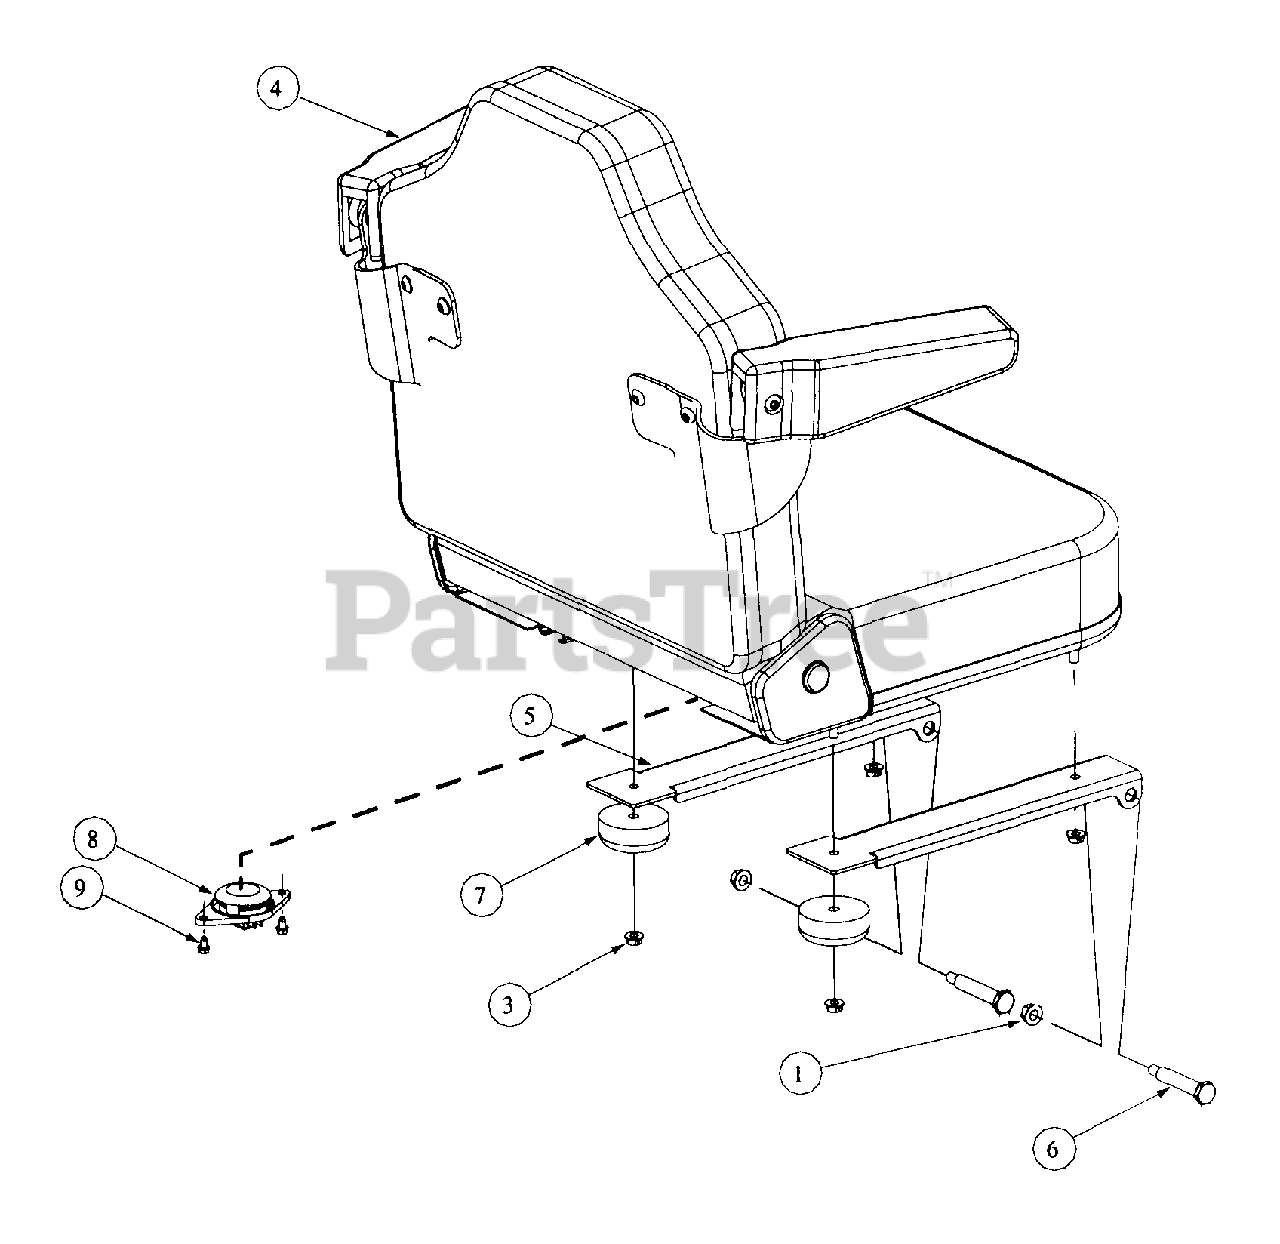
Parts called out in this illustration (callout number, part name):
1	Nut, Hex 3/8-16 Flange Lock
3	Lock Nut, Hex Flange, 5/16-18
4	Adjustable Seat
5	Mounting Bracket, Seat
6	Shoulder Screw, .50x2.345, 3/8-16
7	Grommet, 2.5 OD x 1.0 Long
8	Seat Switch
9	Screw, TT, 1/4-20, .500, Hex
